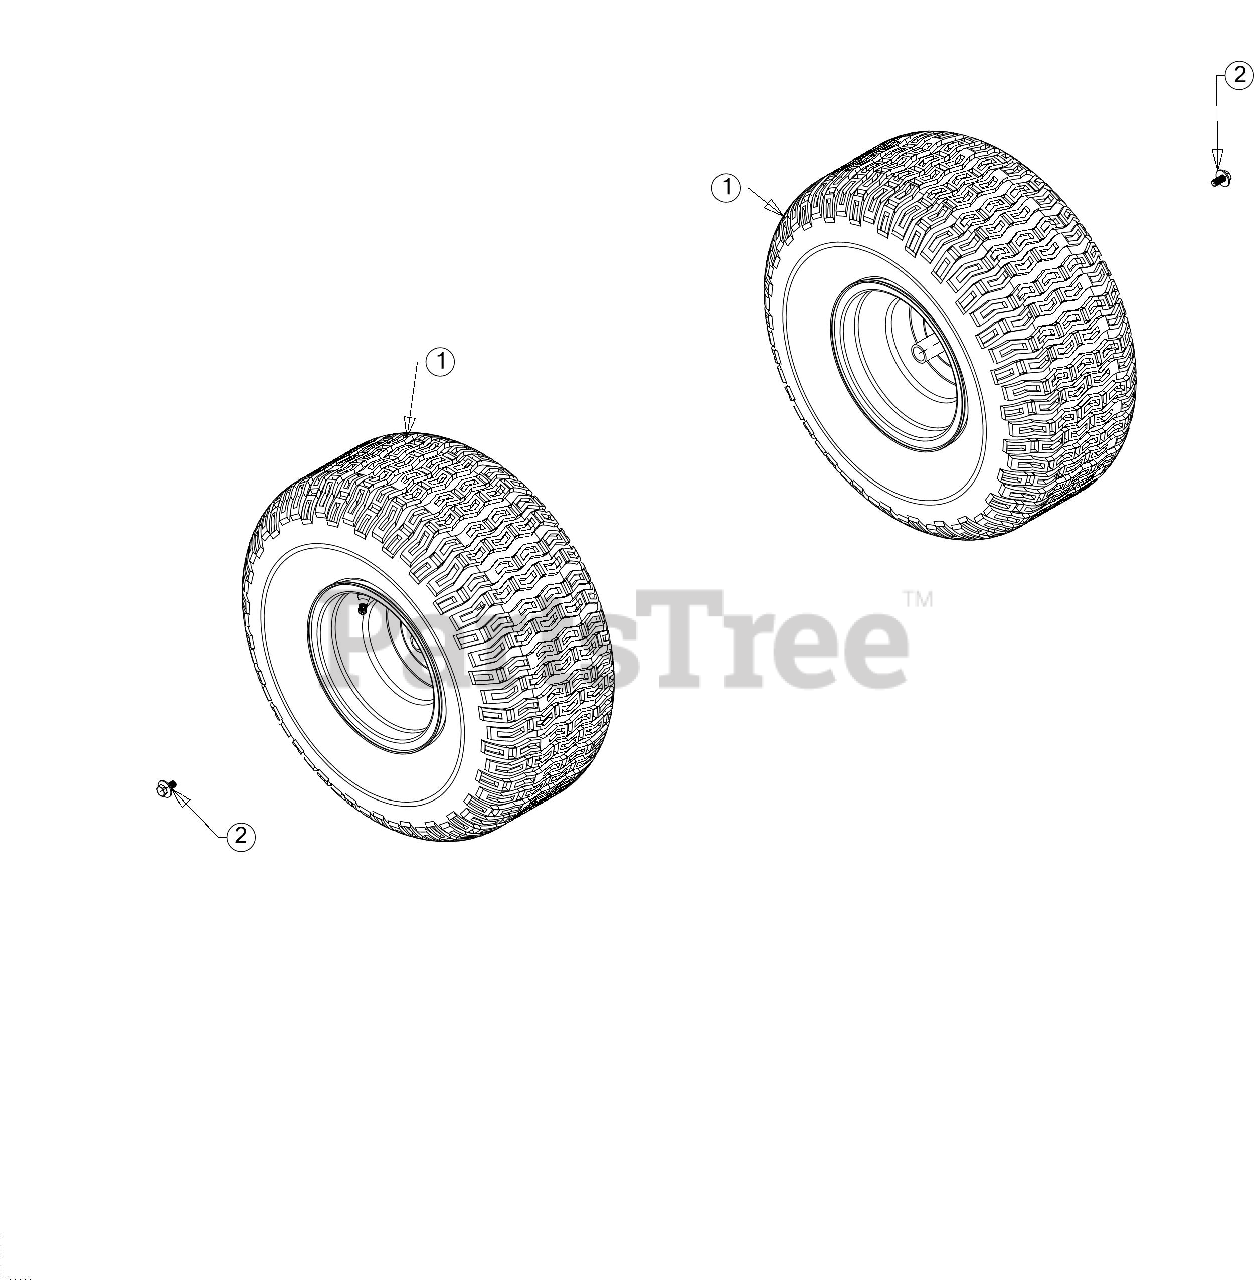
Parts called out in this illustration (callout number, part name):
1	WHEEL ASSEMBLY (20 X 8 X 8)
1	RIM ASSEMBLY (8.0 X 7.0 X .750)
1	TIRE-20 X 8 X 8 RN
1	TUBELESS VALVE
2	SCREW 5/16-24 X .750 GR5
